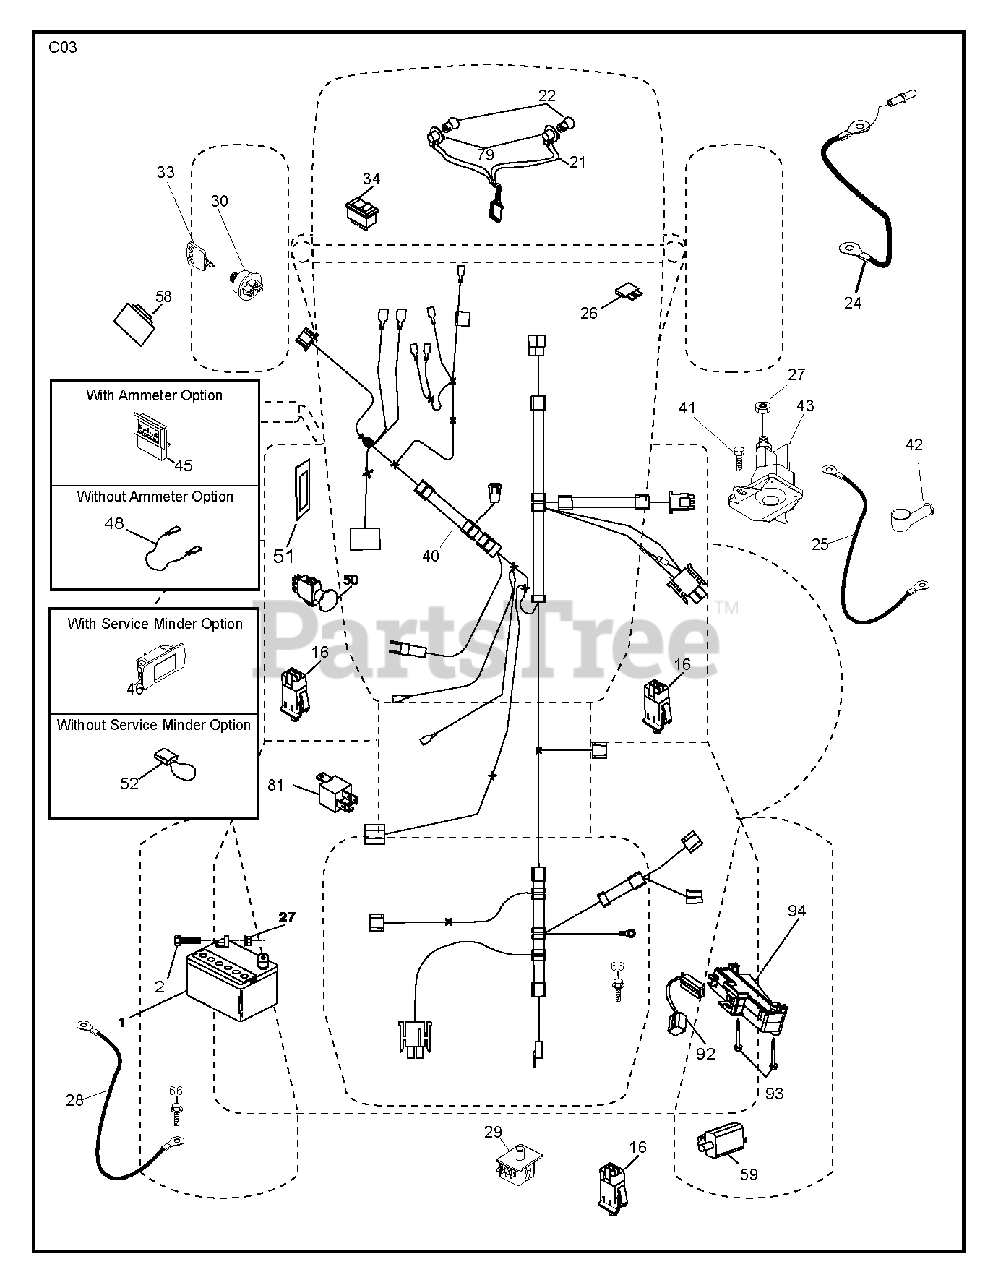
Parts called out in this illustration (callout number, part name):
1	REPL BY 532 12 38-99
16	SWITCH INTERLOOK PUSH-IN
21	HARNESS ASSY LIGHT
22	LIGHTBULB
24	CABLE BATTERY 6 GA. 11" RED
25	CABLE BATTERY
26	FUSE 20AMP
27	NUT
28	CABLE GROUND
29	SWITCH.SEAT.DP W/RAMPS
30	SWITCH.IGN.DELTA.W.LGH.ROS
33	KEY.CHAIN.BLISTER.PACK.GEN.INT
34	SWITCH LT
42	TERMINAL COVER
43	SOLENOID.W/BRASS.PLUNG
50	PTO SWITCH
51	RETAINING RING
52	WIRE PROTECTION LOOP
58	BUZZER
79	BULB HOLDER ASM.
81	RELAY.ASSY.T
92	HARNESS.PIGTAIL.CONSLE
93	SCREW.PLASTITE
94	MODULE.REVERSE.ROS
